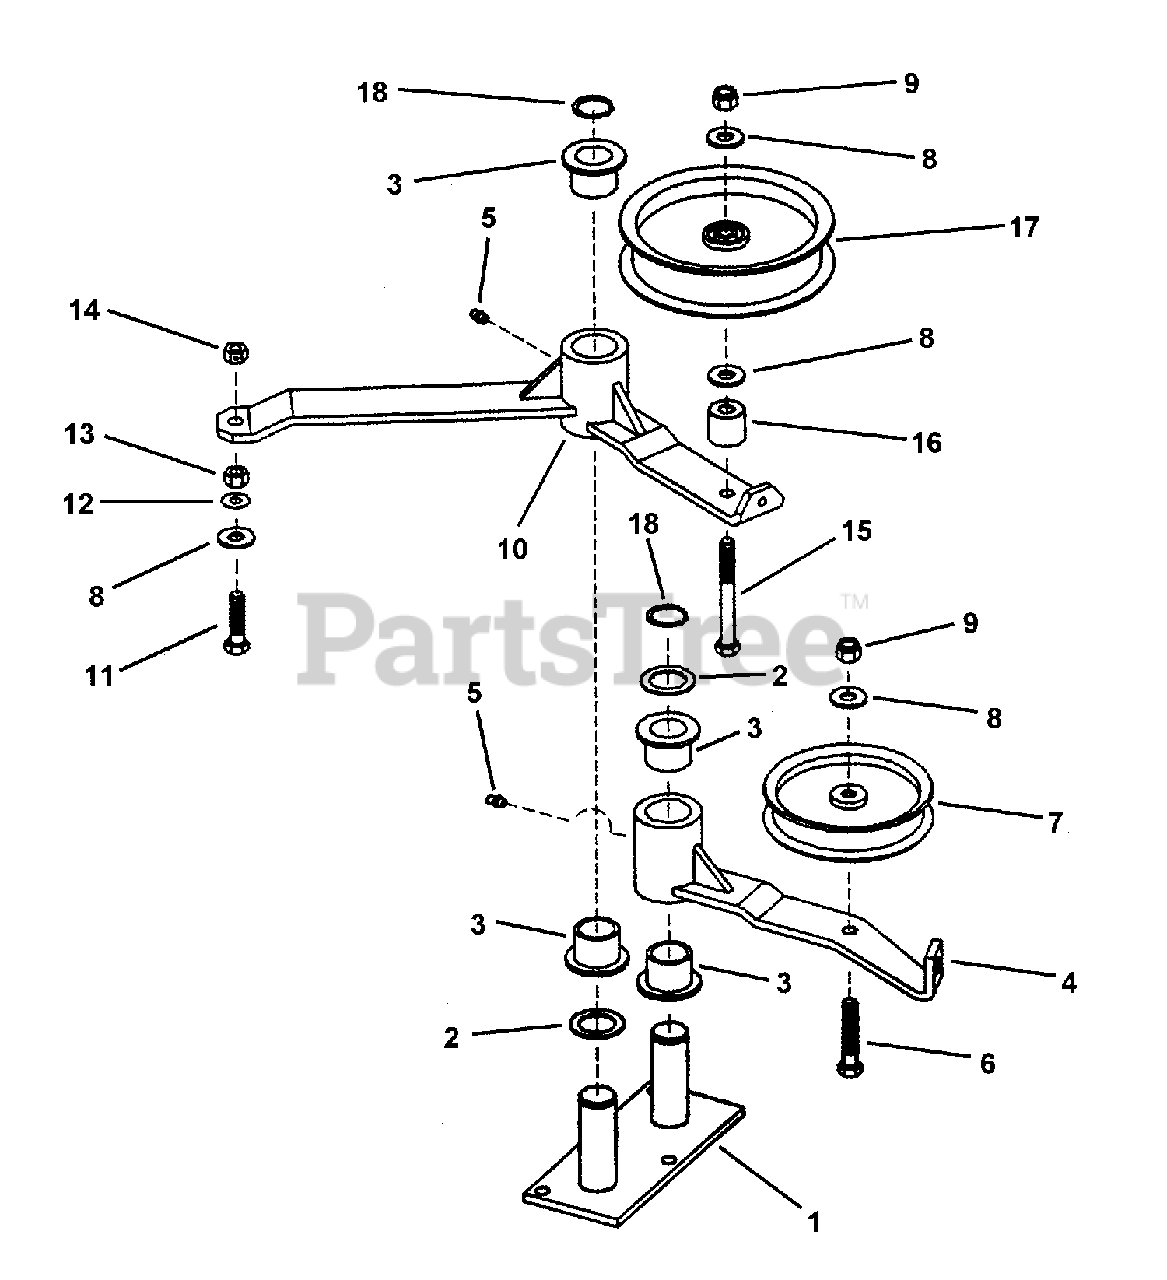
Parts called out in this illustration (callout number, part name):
1	WELDMENT, Idler Pivot
2	BUSHING, Machine
3	BUSHING, Flange
4	WELDMENT, Secondary Idler Arm
5	LUBE FITTING, 1/4-28 Straight
6	BOLT, 3/8-16 X 2, GD5, CZ
7	PULLEY, Idler
8	WASHER, .44 x 1.0 x .08 Flat
9	NUT, 3/8-16 HEX NYLON LOCK
10	WELDMENT, Primary Idler Arm, SPA521
11	SCREW, 3/8-16 x 1-1/2" Hex Head Cap, GR 5
12	RETAINER, 3/8" Bolt
13	NUT, 3/8-16 Hex, GR 5
14	NUT, 3/8-16 Hex Center lock
15	BOLT, 3/8-16 x 3-1/4" Hex Head, GR 5
16	SPACER, Idler Pulley
17	PULLEY, Idler (5.00 O. D.)
18	RING, 1" External Retaining
